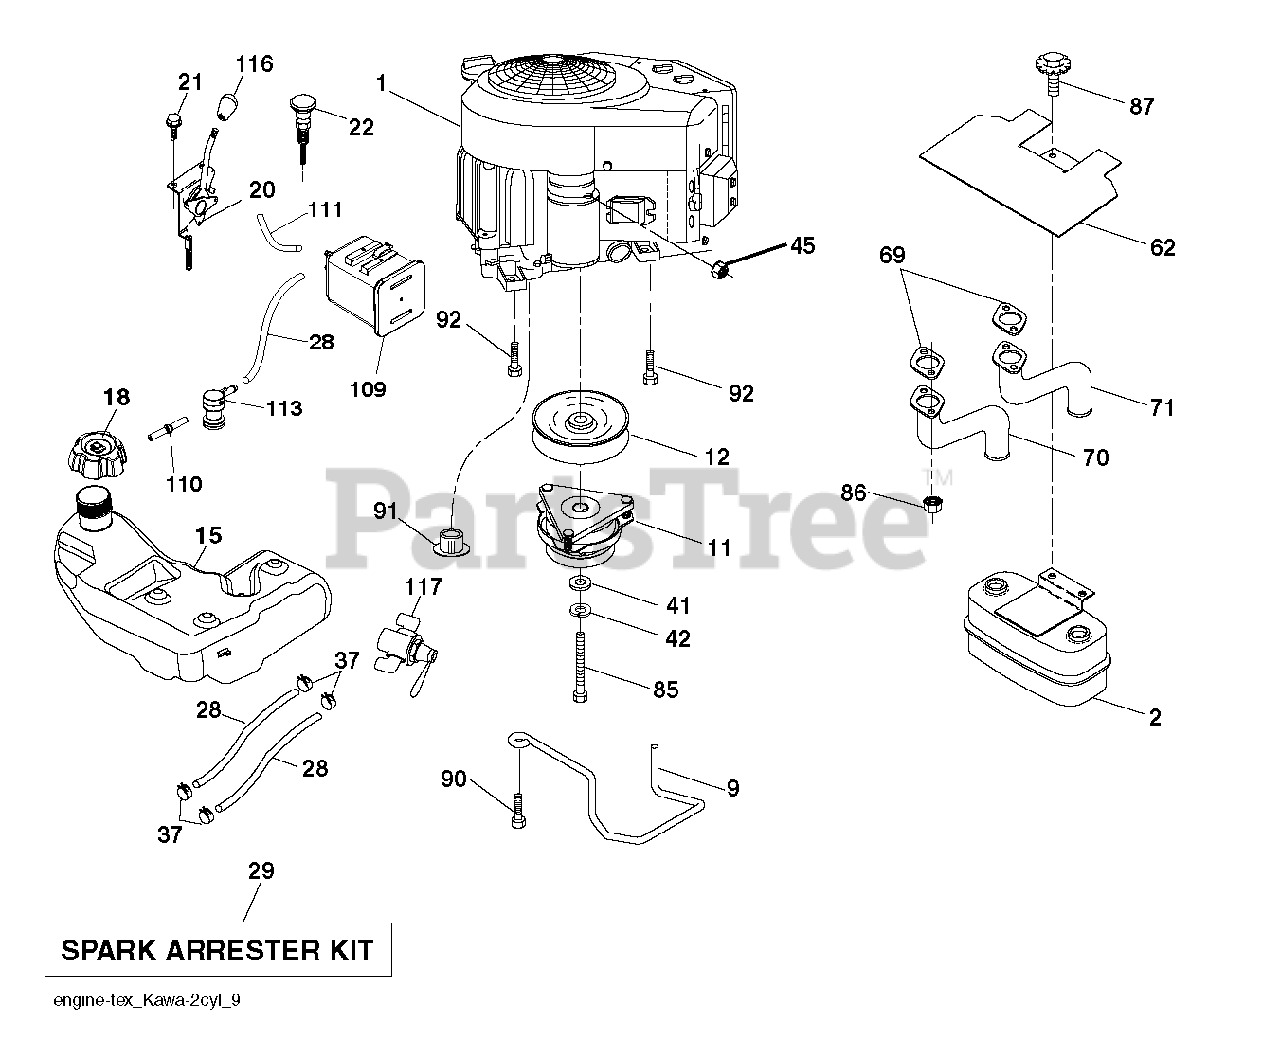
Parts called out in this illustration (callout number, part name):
2	MUFFLER.ASM.TWN.EXTNDED.DFLCTR
9	KEEPER BELT ENGINE
11	CLUTCH MZ ZTR GT.48/54"1.125"
12	PULLEY ENGINE
15	TANK.ASM.4.GAL.CARB.2.PORT.REA
18	CAP.FL.R.3'N/CARB.H.CROWN.498
20	CONTROL.THROTTLE.PRO.
21	SCREW.#10 X 0.750.BOS
22	CONTROL, CHOKE
28	LINE.FUEL.64"REAR.EMIS
29	KIT.SPARK ARRESTOR 794945 B&S
37	HOSE CLAMP
42	LOCKWASHER
45	NUT
62	SHIELD.HEAT.MUFFLER
70	TUBE.EXHAUST.LH.FR961/FR730
71	TUBE.EXHAUST.RH.FR961/FR730
85	BOLT HEX 7/16-20 X 3.75 GR. 5
86	BOLT, 5/16-18 X 1 3/4
87	BOLT, 5/16-18 X 1 3/4
90	SCREW 3/8-16X1
91	BUSHING.1.375OD
92	SCREW 3/8-16X1
109	CANNISTER, CARBON
110	VALVE.ASM.ANTI-SLOSH
111	RP PURGE LINE
113	VALVE.SLANT.CARTRDG.90 DEG.TEX
116	KNOB - SHIFT
117	VALVE FUEL RESERVE
